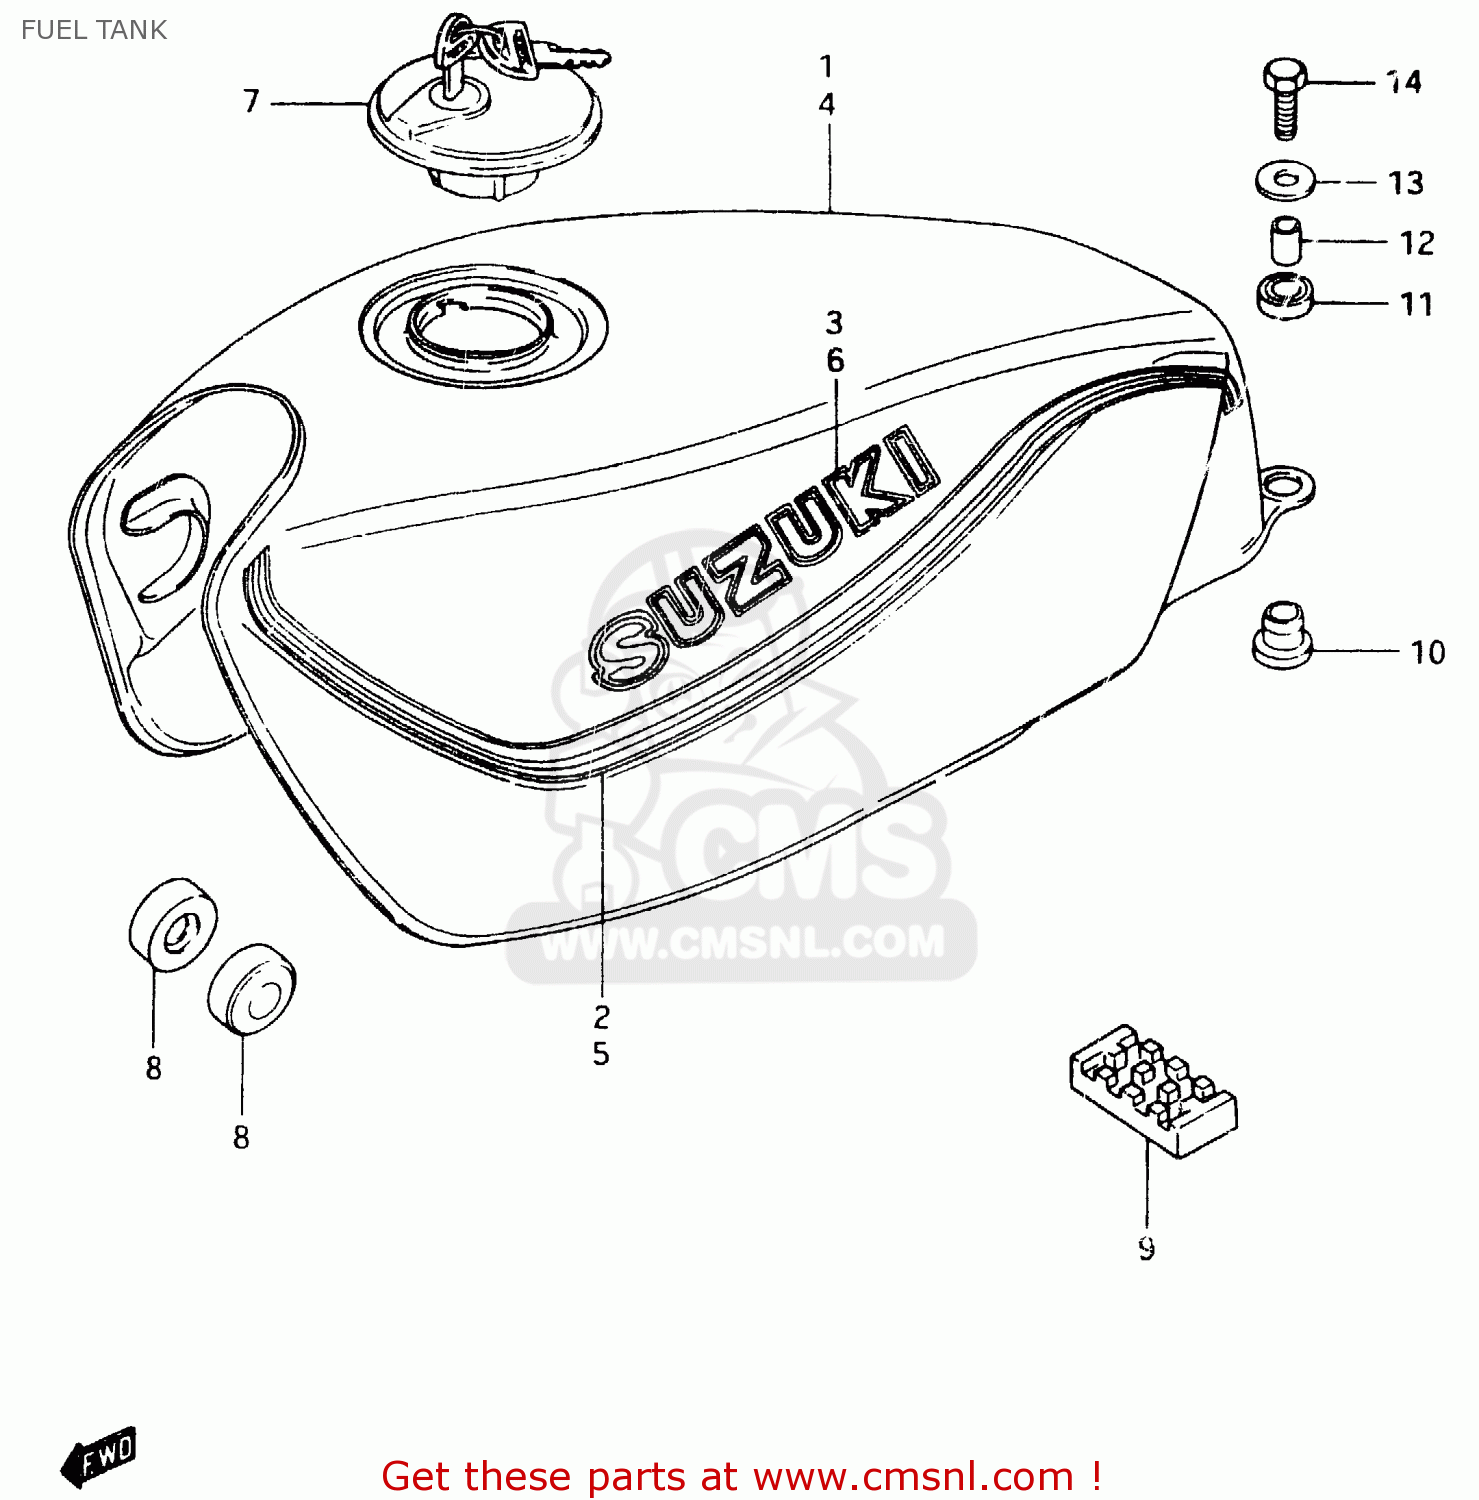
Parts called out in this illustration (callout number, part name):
1	TANK,FUEL
2	TAPE SET
3	EMBLEM
4	TANK, FUEL
5	TAPE SET
6	EMBLEM,FUEL TANK
7	CAP SET,FUEL TANK
8	CUSHION
9	CUSHION,FUEL TANK CTR
10	CUSHION
11	CUSHION
12	SPACER
13	WASHER (6.5X24X1.6)
14	BOLT
